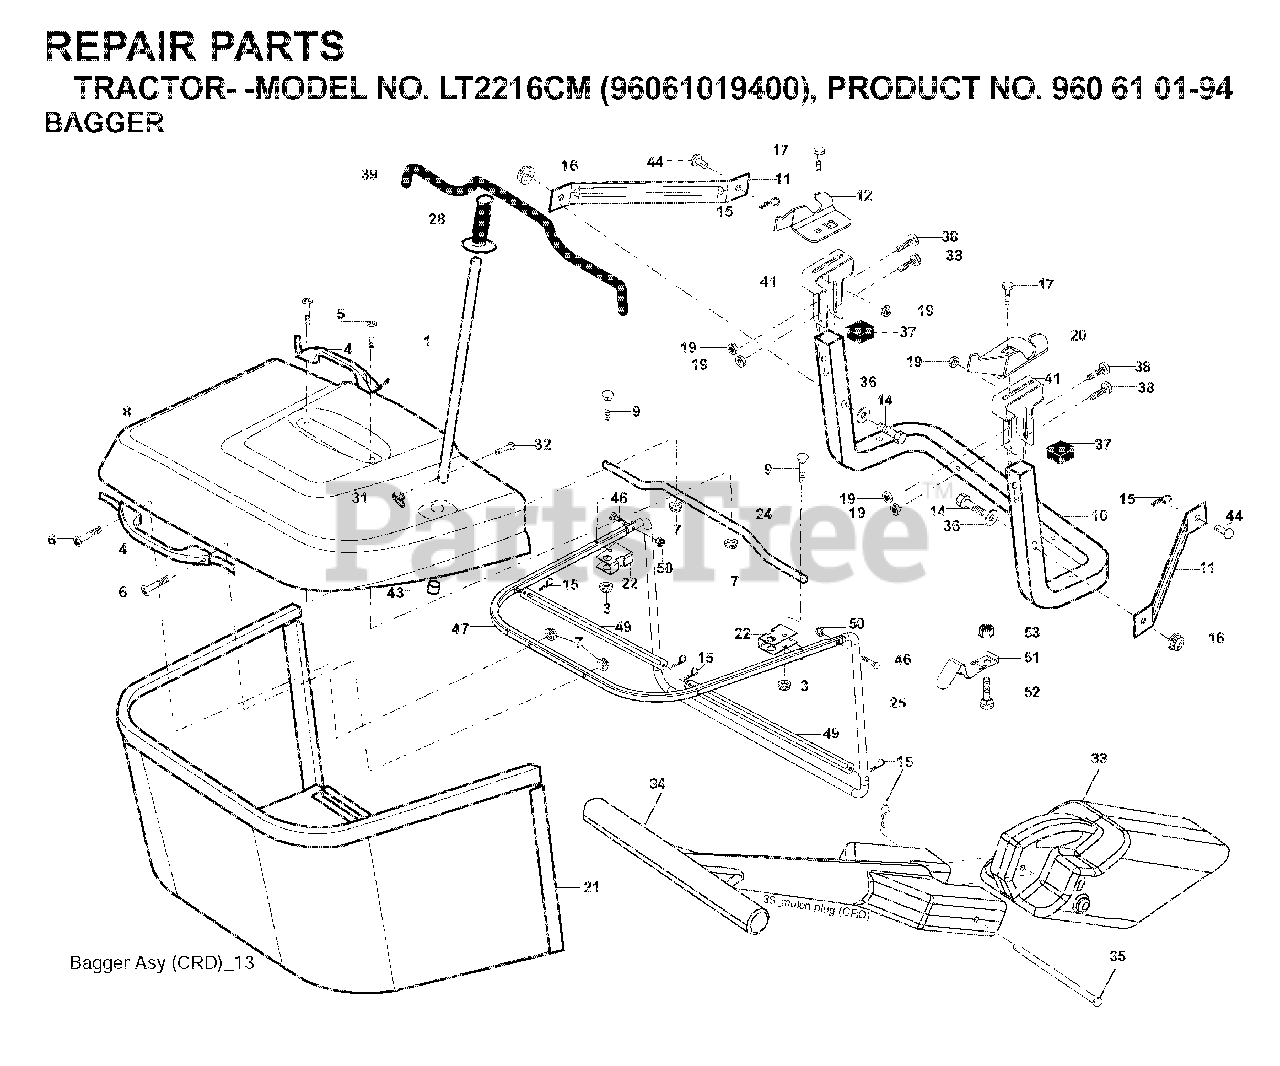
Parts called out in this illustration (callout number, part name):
1	TUBE HANDLE
3	NUT T
5	SCREW.PAN.HEAD
11	BRACKET
14	BOLT-HEX EAK
15	RETAINER-SPRNG RB
16	NUT LOCK FLG 3/8-16 UNC
17	BOLT
19	NUT LOCK HEX FLANGE 5/16-18
20	BRKT.PIVOT.RH.CRD
21	BAGGER.ASM.CRD.2007
22	BRACKET
24	TUBE
28	GRIP.HANDLE.BLACK
31	RETAINER CLIP
32	RIVET,DRILLED
33	PLUG
35	PIN
38	BOLT.5/16-18X2.5
41	BRKT, BAGGER
43	PLUG, TUBING END
46	BOLT.CARRIAGE.5/16-18
50	NUT.71038.31-18.HEX.NYLOCK
53	NUT
54	BOLT
